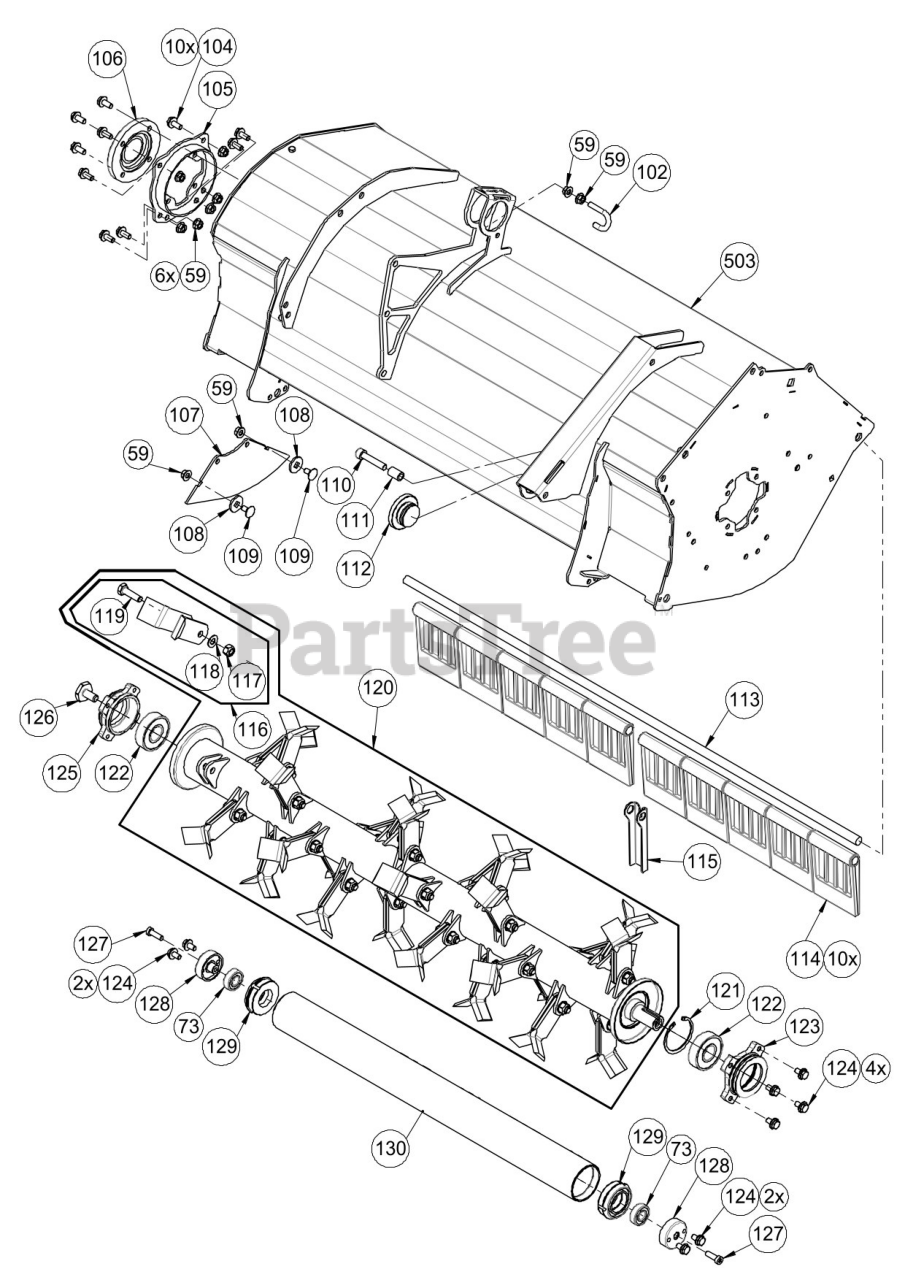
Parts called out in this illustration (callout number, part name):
59	NUT, FLG SLF LK M8 CL 8 ZCC
73	BRG,BALL 6202-2RSH (15X35X11)
102	HOOK, THREADED
104	BLT, SER FLG M8X18 VERBUS RIPP
105	SHIELD, BEARING
106	COVER, BEARING
107	PLATE, LOCKING
108	WSHR, FLT V M9.0 DIN 440 ZCC
109	BLT, RHSN M8X 16 DIN 603 8.8 ZCC
110	SCR, SKH M10X50 DIN ISO 4762 10.9
113	ROD, FLAP PIVOT
114	FLAP, BRUSH DEFLECTOR
115	SPACER, FLAP (DEFLECTOR)
116	KIT, FLAIL BLADE
117	NUT, LK V-M10 DIN 980
118	WSHR, WAVE B10 DIN 137-B
119	BLT, HEX M10X37 DIN 931 10.9
120	KIT, FLAIL SHAFT (W/28 FLAILS SETS)
121	RG, RTNG-INT 62X2 DIN 472
122	BRG,BALL 6305-2RSH (25X62X17)
123	HOUSING, FLANGE BEARING (RH)
124	BLT, SER FLG M8X14 VERBUS RIPP
125	HOUSING, FLANGE BEARING (LH)
127	TORX SHCS M8X25 SIMILAR TO DIN 7984 8.8
128	SHIELD, BEARING MOUNTING
129	FLANGE, BEARING (ROLLER)
503	DECK, FLAIL MOWER
